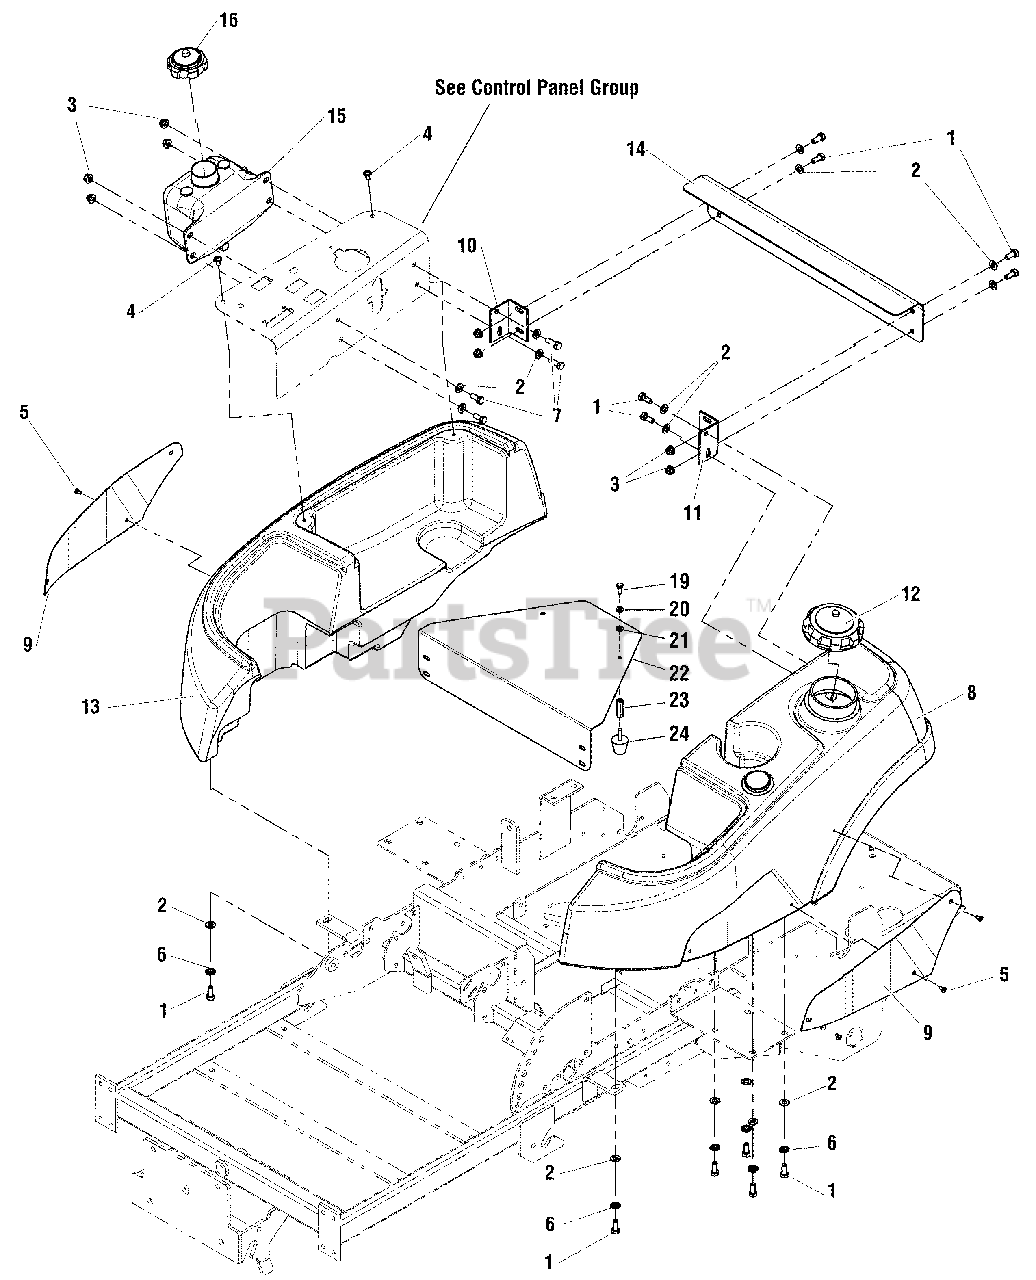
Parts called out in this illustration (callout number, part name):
1	BOLT, 5/16-18 X 3/4 GD5
2	WASHER, 5/16" SAE
3	NUT, 5/16-18 HEX NYLOCK FLANGE
4	SCREW, 1/4-20 X 1/2 ALLEN BH
5	SCREW, #10-24 X 3/8 ALLEN BHBZ
6	WASHER, 5/16 LOCK YZ
7	BOLT, 5/16-18 X 1 GD5 YZ
8	TANK, FUEL - LH, 2008 CONZ
9	PLATE, FUEL TANK BADGE
10	BRACKET, REAR SUPPORT - RH
11	BRACKET, REAR SUPPORT - LH - RED
12	CAP, GASOLINE, VENTED
13	TANK, FENDER, CONZ, RH
14	PLATE, SUPPORT, REAR TANK
15	TANK, 2 QT HYDRAULIC
16	CAP, HYDRAULIC RESERVOIR
19	BOLT, 5/16-18 X 3/4 GD5
20	WASHER, 5/16 LOCK YZ
21	WASHER, 5/16" SAE
22	PLATE, ENGINE GUARD, CE - RED
23	NUT, COUPLING, 5/16-18 X 1-3/4 CZ
24	BUMPER, RUBBER, 5/16-18
